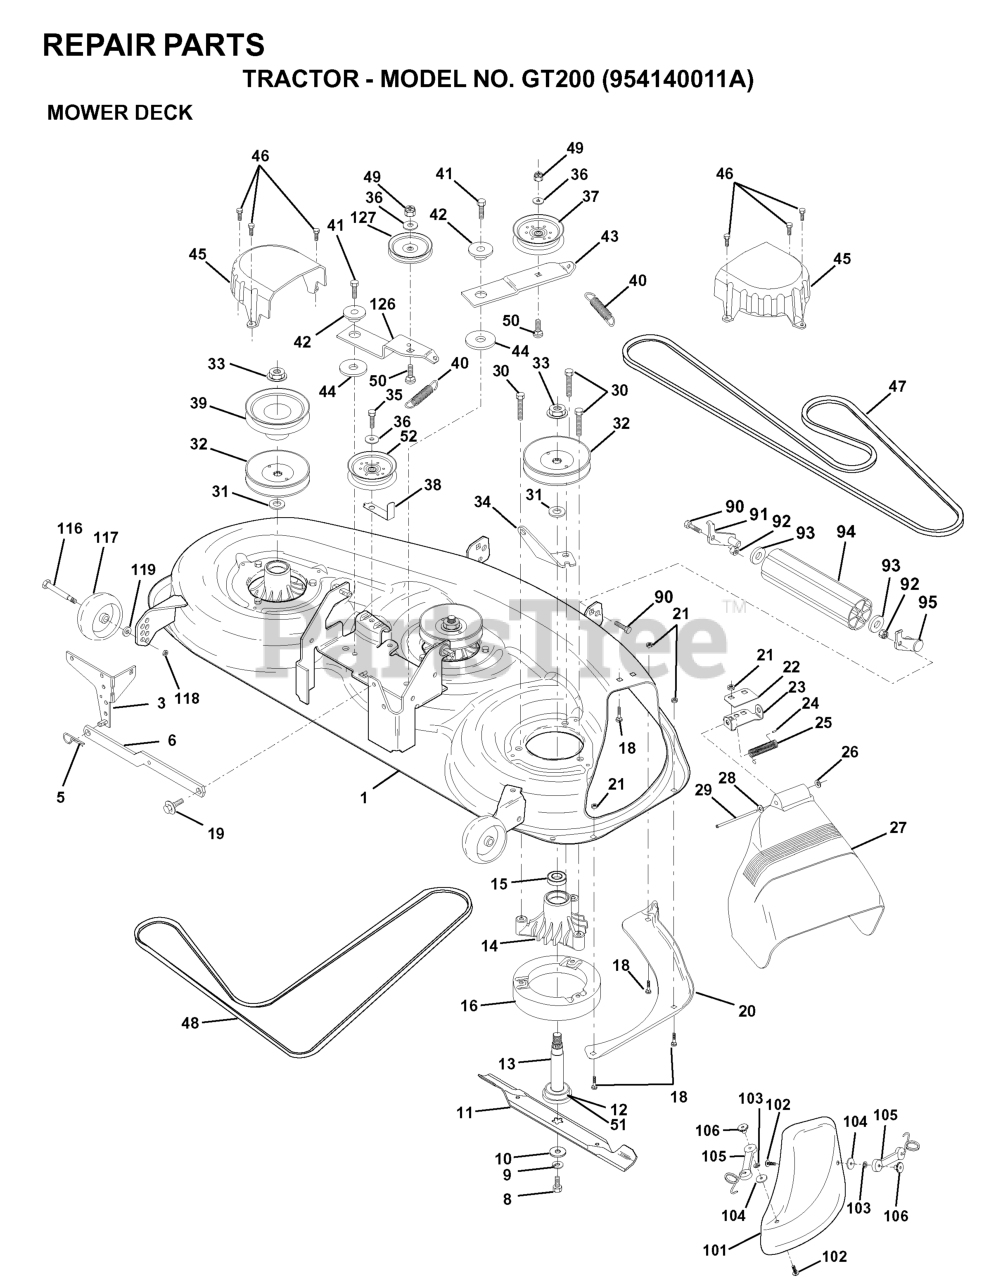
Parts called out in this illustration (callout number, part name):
1	HOUSING MOWER
3	BRACKET SWAY BAR
5	RETAINER-SPRNG RB
6	REAR SUSP ARM
8	BLADE BOLT
9	LOCKWASHER
10	WASHER.BLADE
11	MULCH BLADE 46"
12	BEARING.BALL.#6204.(MANDREL)
13	SHAFT.ASM.W/BEARING
14	HOUSING.MANDREL.44/46" VENT
16	STRIPPER
18	BOLT
19	BOLT SHD 5/16-18
20	BAFFLE, VORTEX MOWER 46"
21	LOCKNUT
22	STIFFENER BRACKET
23	DEFLECTOR BRACKET
24	CAP-SLEEVE LT
25	SPRING TORSION
26	NUT PUSH M
27	SHIELD, DEFLECTOR MOWER
28	Washer 11/32 x 5/8 x 16 Ga SD
29	ROD.HINGE
30	SCREW
31	WASHER
32	PULLEY, MANDREL
33	NUT
34	ANCHOR, SPRING DECK 46"
35	SCREW LT
36	WASHER
37	FLAT IDLER PULLEY
38	KEEPER
39	PULLEY.DRIVEN.DECK.46"
40	SPRING.SEC.44"VEN
41	SCREW
42	SPACER RETAINER
43	ARM IDLER DECK 46"
44	HARDENED WASHER
45	COVER MANDREL 46
46	SCREW.1/4-20X5/8
47	BELT V SECONDARY
48	V-BELT PRIMARY 50"
50	BOLT.3/8-16X1.50
51	WASHER FELT
52	PULLEY IDLER FLAT 46 PRI DRIVE
90	BOLT
91	BRACKET LH (A)
92	NUT
93	Washer 1 17/32 X 7/8 X 16 Ga
94	NOSE ROLLER
95	BRACKET RH (B)
101	COVER.MULCH.46"3-BLADE.(2 2)
102	SCREW
103	LOCKWASHER #10
105	LATCH ASSEMBLY
106	WELDNUT
116	BOLT, SHOULDER
117	WHEEL GAGE DONUT
118	LOCKNUT
119	WASHER.5/16.FLAT.STE.STD.
126	ARM IDLER PRIM 46
127	PULLEY.IDLER.4.25
